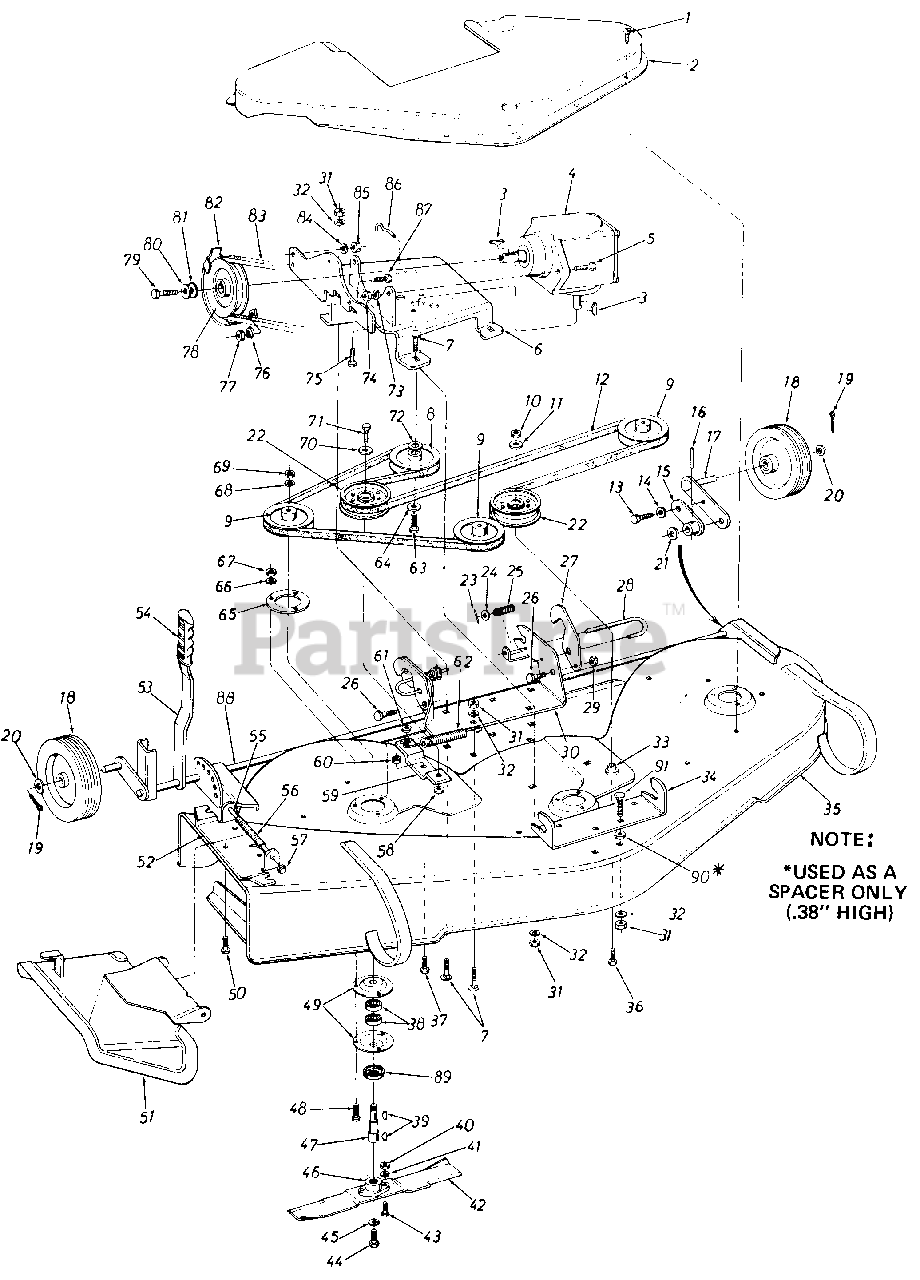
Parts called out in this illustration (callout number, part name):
1	Hex "B"-Tapp Scr. 1/4-20 x 3/8"Lg.
2	Belt Cover
3	#9 Hi-Pro-Key 3/16x 3/4" Dia.
4	Right Angle Drive
5	Hex Scr. 3/8-16 x 1.25" Lg.*
6	Deck Brkt. Ass'y.
7	Carriage Bolt 5/16-18 x .75" Lg.*
8	Deck Pulley-Drive
9	Deck Spindle Pulley
10	Hex Nut 3/8-16 Thd.*
11	Fl.-Wash. .385 I.D. x .87 O.D.
12	"V"-Belt "A" Section 100" Lg.
13	Hex Scr. 3/8-16 x 1.00" Lg.*
14	Bell.-Wash. .400 I.D. x .88 O.D.
15	Wheel Adj. Plate Ass'y.
16	Spring Pin Spir. 1/4" Dia. x .1.50" Lg.
17	Deck Wheel Brkt. Ass'y
18	Wheel Ass'y. (Plastic)
19	Cotter Pin 5/32" Dia. x 1.00" Lg.*
20	Fl.-Wash. .635 I.D. x .93 O.D. x .060
21	Spacer .755 I.D. x 1.25 O.D. x .180
22	Deck Idler
23	Spirol Pin-1/8" Dia. x .812 Lg.
24	Fl.-Wash. .406 I.D. x .734 O.D.
25	Compression Spring .47" O.D. x 1.93
26	Shoulder Bolt
27	Hanger Lock
28	Release Pin
29	Hex Cent. L.-Nut 5/16-18 Thd.
30	Rear Deck Hanger Ass'y.
31	Hex Nut 5/16-18 Thd.*
32	LockWasher
33	Idler Adapter
34	Front Deck Hanger
35	Deck Ass'y.
36	Hex Scr. 3/8-16 x 2.50" Lg.*
37	Shld. Scr. .625 Dia. x .960
38	Ball Bearing .787 I.D. x 1.85 O.D.
39	#6 Hi-Pro-Key 5/32" x 5/8" Dia.
40	Hex Nut 5/16-24 Thd-.*
41	L-Wash. 5/16" Scr.*
42	Blade 14.75"
43	Hex Scr. 5/16-24 x 1.00" Lg.*
44	Hex Scr. 3/8-24 x 1.50" Lg.*
45	L-Wash. 3/8" Scr. Heavy Duty
46	Blade Adapter Kit
47	Spindle
48	Hex Scr. 5/16-24 x 1.00" Lg.*
49	Bearing Housing
50	Hex Scr. 1/4-28 x .50" Lg.*
51	Chute Cover Ass'y. Comp.
52	Adapter Ass'y.
53	Deck Wheel Adjustment Handle
54	Grip
55	Hinge Pin
56	Torsion Spring
57	Pushnut 1/4" Rod
58	Hex Cent. L.-Nut 3/8-24 Thd.
59	Deck Spring Idler Brkt.
60	Hex Ins. L-Nut 3/8-16 Thd.
61	Hex Cent. L.-Nut 5/16-18 Thd.
62	Extension Spring
63	Hex Scr. 5/16-18 x 2.00" Lg.*
64	Bell.-Wash.
65	Deck Reinforcement Plate
66	L-Wash. 5/16" Scr.*
67	Hex Nut 5/16-24 Thd. *
68	L.-Wash. 5/8" Scr;*
69	Hex Jam L.-Nut 5/8-11 Thd.
70	Fl.-Wash. .385 I.D. x .87 O.D.
71	Shld. Scr. .625 Dia. x .960
72	Fl.-Wash. 5/16" I.D. x 1.12" O.D.
73	L.-Wash. 3/8" Scr.*
74	Hex Nut 3/8-16 Thd.*
75	Hex Scr. 1/4-20 x 1.25" Lg.*
76	L.-Wash. 5/16" Scr.*
77	Hex Nut 5/16-18 Thd.*
78	4.75 O.D. Pulley-Input
79	Hex Scr. 5/16-18 x 2.00" Lg.*
80	Bell.-Wash.
81	Fl.-Wash 5/16" I.D. x 1.12 O.D.
82	Belt Guard
83	V-Belt "A" Section 1/2" x 56" Lg
84	L-Wash. 5/16" Scr.*
85	Hex Nut 5/16-18 Thd.*
86	Spring Tension Anchor Pin
87	Hex Scr. 5/16-18 x .75" Lg.*
88	Wheel Brkt. Shaft Ass'y.
89	Bearing Shield
90	Hex Nut 3/8-16 Thd.
91	Carriage Bolt 5/16-18 x 1" Lg.
